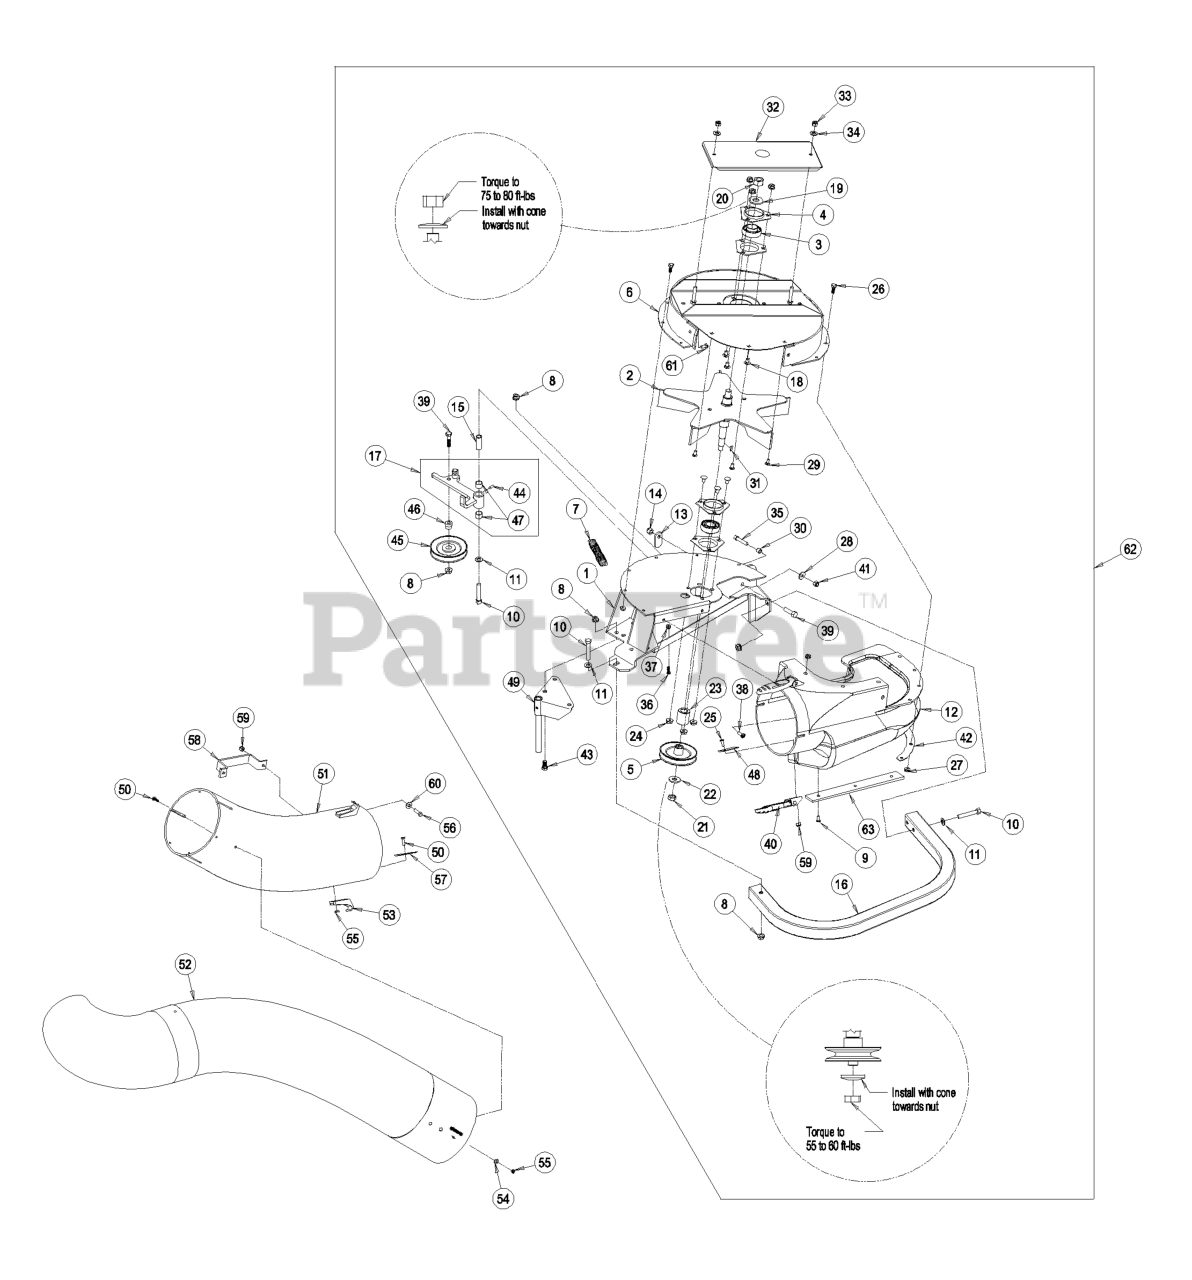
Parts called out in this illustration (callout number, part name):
1	WLD,BLOWER MOUNT
2	IMPELLER
3	BEARING
4	HOUSING-FLANGE
5	SHEAVE
6	ASM, UPPER HSG
7	SPRING-IDLER
8	NUT-HHF, WHIZ
9	RIVET-BLIND
10	SCREW-HH
11	WASHER-FLAT
12	ASM,BLOWER CHUTE LZ
13	LATCH-CATCHER, GRASS
14	NUT-LOCK, NI
15	BUSHING
17	ASM, IDLER ARM - SERVICE
18	SCREW-CARR
19	WASHER-SPRING
20	NUT-HEX
21	NUT-JAM
22	WASHER-SPRING
25	SCREW-HH
26	SCREW-HH
28	WASHER-SPRING
29	SCREW-CARR
30	BUSHING, LOCATOR
31	KEY-WOODRUFF
32	ASM, BEARING COVER
33	NUT-LOCK, NI
34	WASHER-FLAT
35	SCREW-HSH
36	SCREW-HEAD, TRUSS
39	SCREW-HH
40	LATCH-RUBBER
41	NUT-HEX
42	PLATE-BACKING, BLOWER
43	SCREW-HH
44	FITTING-GREASE
46	HUB,SPACER
47	BUSHING
48	PLATE-BACKING
49	PIN-MOUNT
50	SCREW-HWH
51	TUBE-LOWER
52	TUBE-UPPER
53	LATCH-CATCH
54	WASHER-FLAT
55	NUT-LOCK, NI
56	SCREW-HH
57	PLATE-BACKING
59	NUT-LOCK, NI
60	WASHER-FLAT
61	BOLT-CARR
62	Asm, Blower
63	PLATE,REINFORCEMENT LARGE
